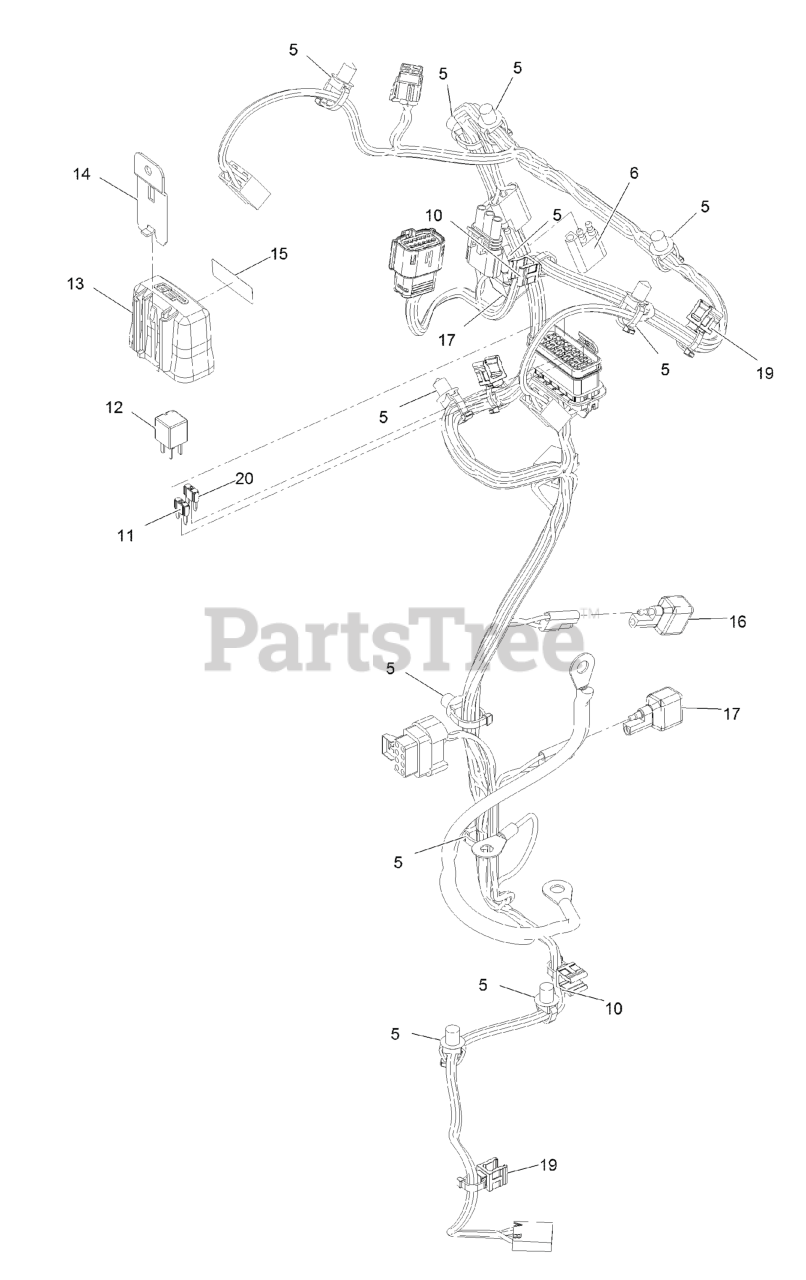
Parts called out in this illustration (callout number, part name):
5	CLIP-TIE
6	Cap-Plug
10	Clip-Edge
11	FUSE-MINI BLADE, 20 AMP
12	RELAY-MICRO
13	COVER-BLOCK, FUSE
14	CLIP-MOUNTING
15	DECAL-FUSE
19	Clip-Edge W/Tie, Perpendicular
20	FUSE-MINI BLADE, 15 AMP
